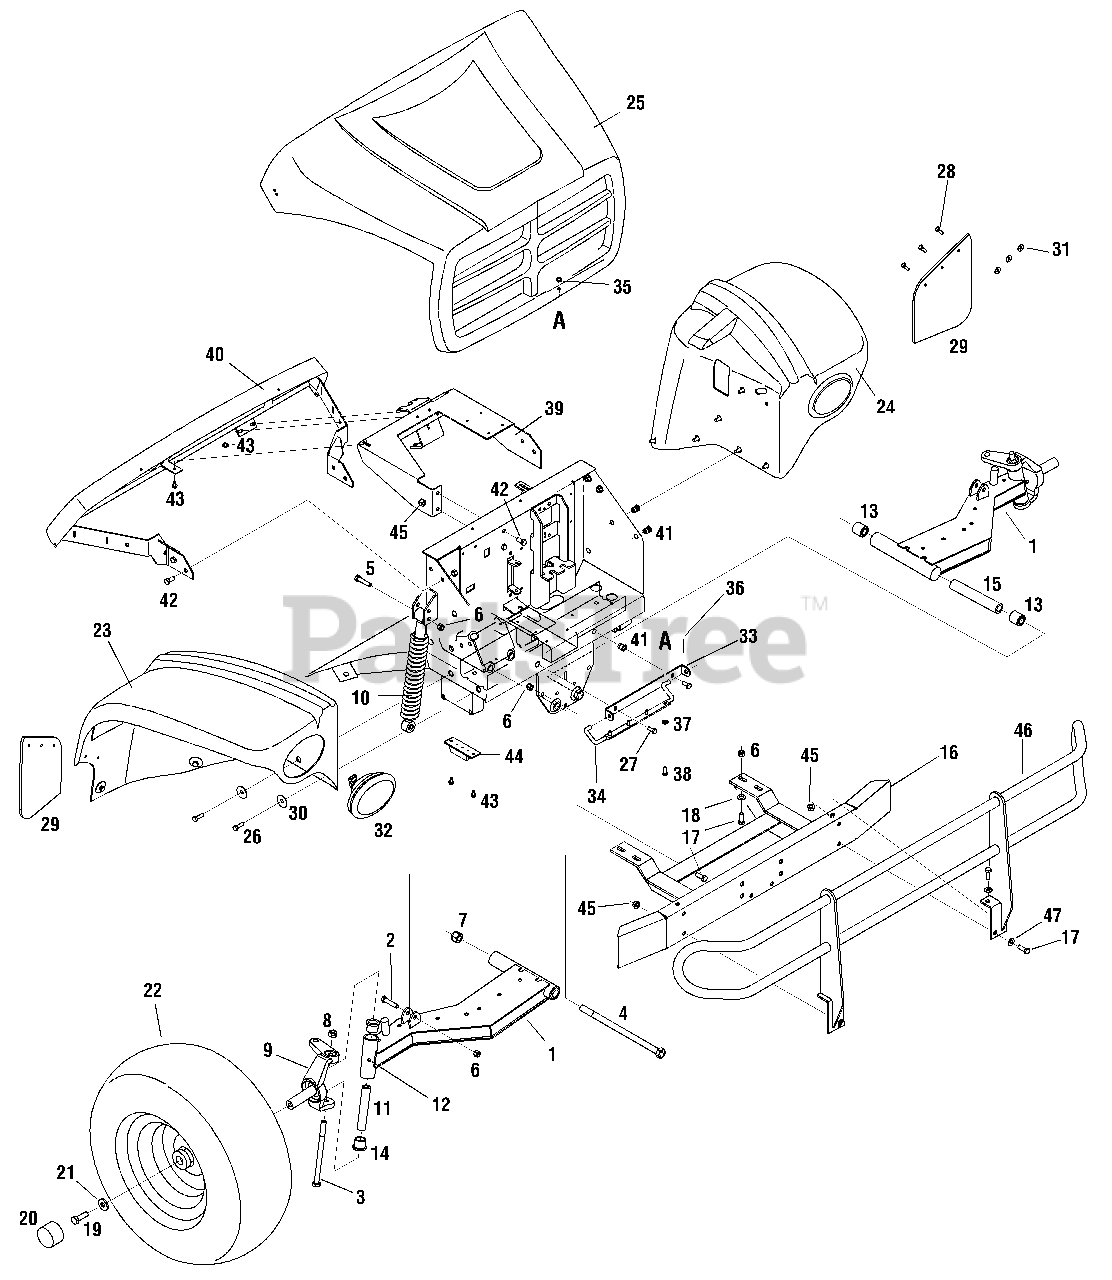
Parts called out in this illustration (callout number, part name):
1	Axle Assembly, Right-front
2	Hex Screw, 3/8-16 x 1.75
3	Hex Screw, 1/2-13 x 7.0, Gr5
4	Hex Screw, 5/8-11 x 11.13, Gr5
5	Hex Screw, 3/8-16 x 2.25
6	Nut, Hex Lock, Nylon, 3/8-16, Gr5
7	Nut, Hex Lock, Nylon, 5/8-11, Gr5
8	Nut, Hex Lock, 1/2-13
9	Steering Control Knuckle, RH
10	Shock Absorber, 2.9 Stroke
11	Tube, .875 x .50 x 4.75
12	Grease Fitting
13	Bearing, .63 ID x 1.19 OD
14	Bushing, Steering
15	Spacer, .645 ID x 1.063 OD
18	Flat Washer, .406 x .875 x .059
19	Hex Screw, 1/2-13 x 1.50, Gr5
21	Flat Washer, .531 x 1.25 x .181
22	Wheel Ass'y, 22 x 11 x 10, RH, All Terr.
23	Panel, Right Fender, Camo
24	Panel, Left Fender, Camo
25	Panel, Hood, Dark Camo
26	Hex Screw 5/16-18 x 1.00 Gr 5
27	Hex Screw, 5/16-18 x .75
28	Pop Rivet
30	Washer, Bell, .39 x 1.38 x .062
31	Flat Washer, .194 x .62 x .063
32	Head lamp Assembly
35	Nut, Hex Lock, 1/4-20
36	Cotter Pin, Internal, 1.42
37	Washer, Flat, .271 x .63 x .065
38	Hex Screw, 1/4-20 x .75
41	Insert Nut, 5/16-18
42	Hex Screw, 3/8-16 x .75
43	Screw, Self-tapping, 1/4-20 x .5
44	Suspension Bumper
45	Flange Lock Nut, 3/8-16
46	Brush Guard
47	Flat Washer, .406ID x .810OD x .051
